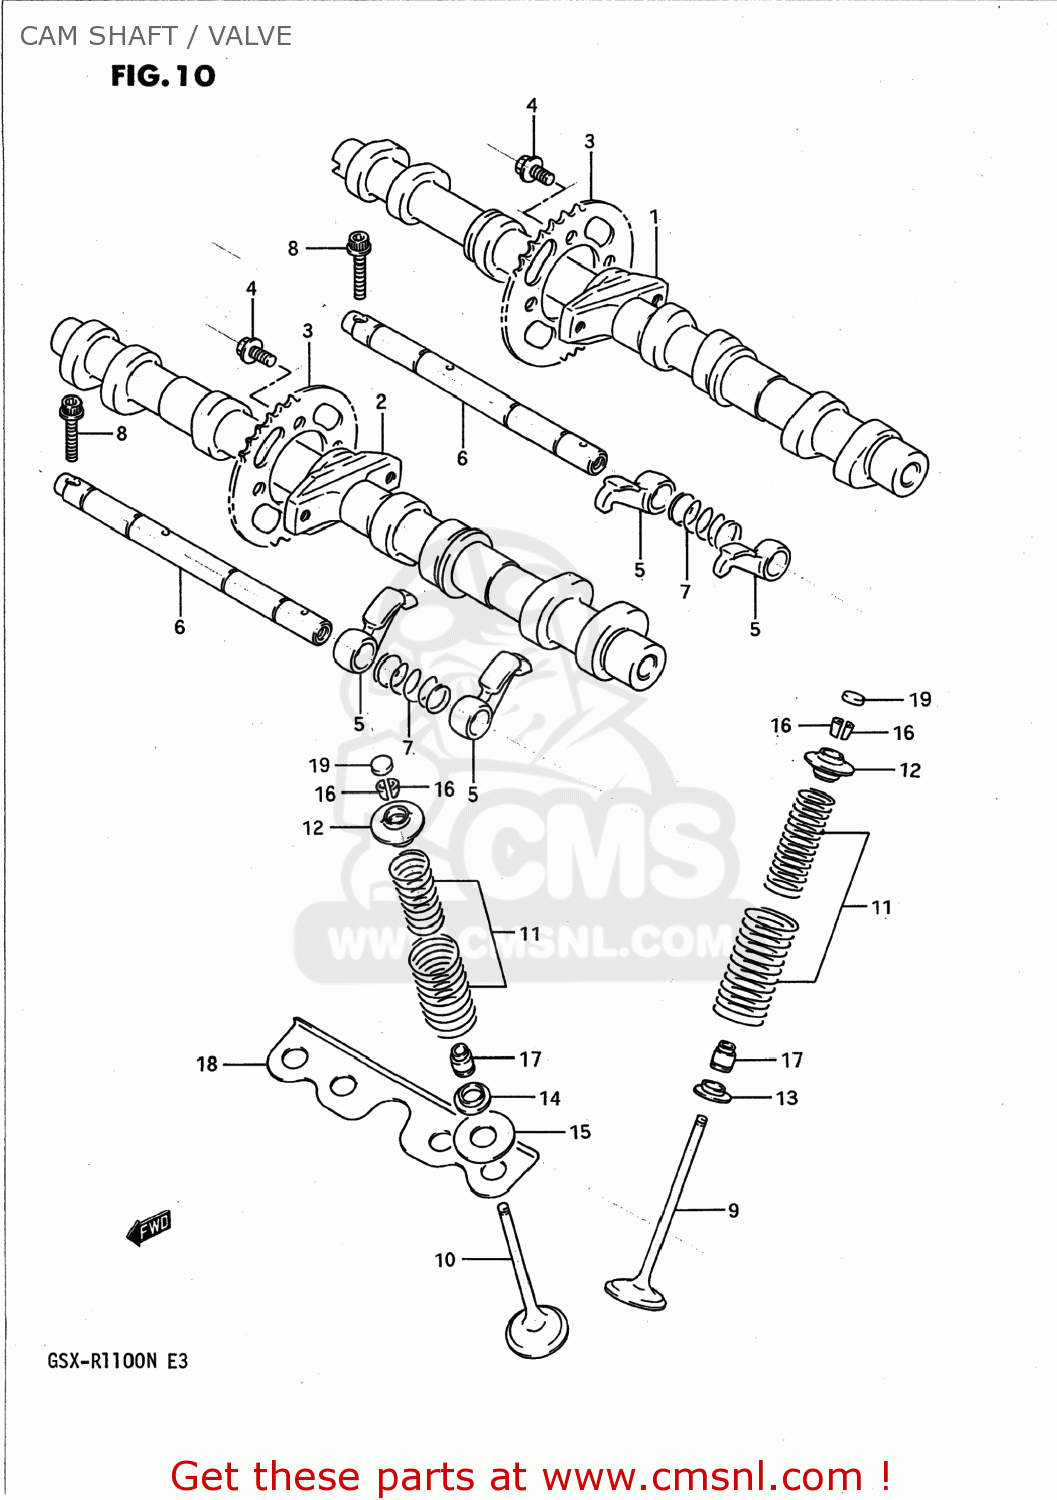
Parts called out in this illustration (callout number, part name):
1	CAMSHAFT,INTAKE
2	CAMSHAFT,EXHAUST
3	SPROCKET,CAMSHAFT
4	BOLT(7X11)
5	ARM,VALVE ROCKER
6	SHAFT,VALVE ROCKER
7	SPRING
8	BOLT
9	VALVE,INTAKE
10	VALVE,EXHAUST
11	SPRING SET,VALVE
12	RETAINER,VALVE SPRING
13	SEAT,VALVE SPRING
14	SEAT,VALVE SPRING
15	SEAT,VALVE SPRING EXH OUTER
16	COTTER VALVE
17	SEAL,OIL(5X10X9.7)
18	PLATE
19	SHIM,TAPPET(T:2.3)
20	SHIM SET,TAPPET
21	CASE,TAPPET SHIM
